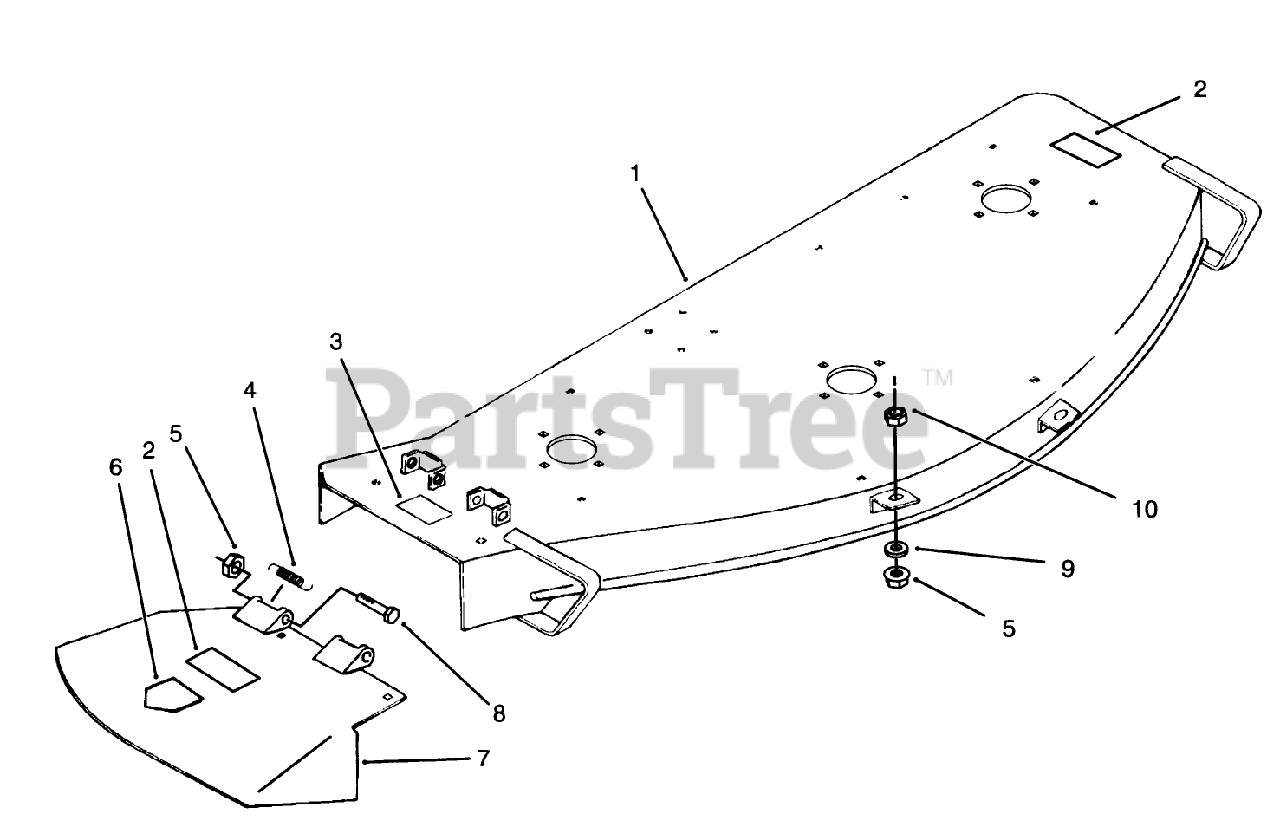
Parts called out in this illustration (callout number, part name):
1	50" Deck & Safety Decal Assy. (Incl. Ref. #2 & 3)
2	DECAL-DANGER, THROWN OBJECT
3	DECAL-DANGER
4	SPRING
5	NUT-LOCK, NI
6	DECAL-DANGER
7	Chute & Safety Decal Assy. (Incl. Ref. #2 & 6)
8	SCREW-HH
9	WASHER-FLAT
10	NUT-FLANGE
